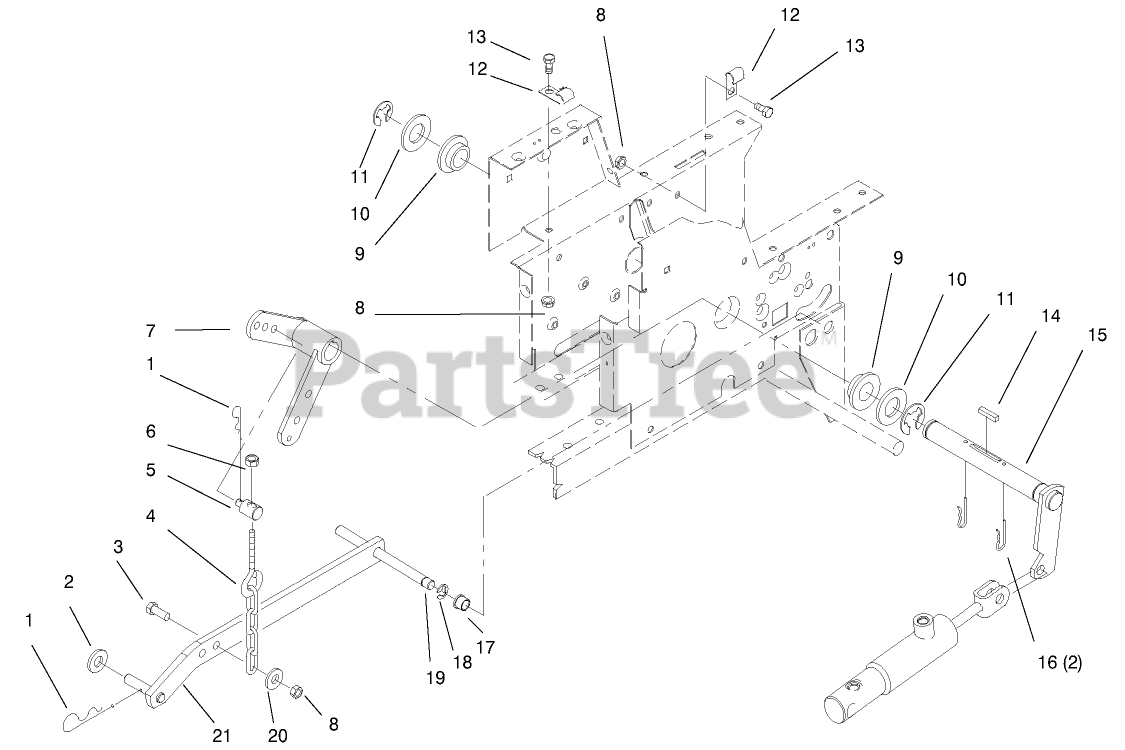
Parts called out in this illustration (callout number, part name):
1	PIN-HAIR
2	WASHER-FLAT
3	SCREW-HH
4	CHAIN-LIFT
5	TRUNNION-LIFT
6	NUT-LOCK, NI
7	LIFT LEVER ASM
8	NUT-LOCK, NI
9	BEARING-FLANGE
10	WASHER-FLAT
11	RING-RETAINING
12	CLIP
13	SCREW-HH
14	KEY-SQUARE
16	PIN-HAIR
17	BUSHING
18	RING-RETAINING, EXTERNAL
20	WASHER-PLAIN
